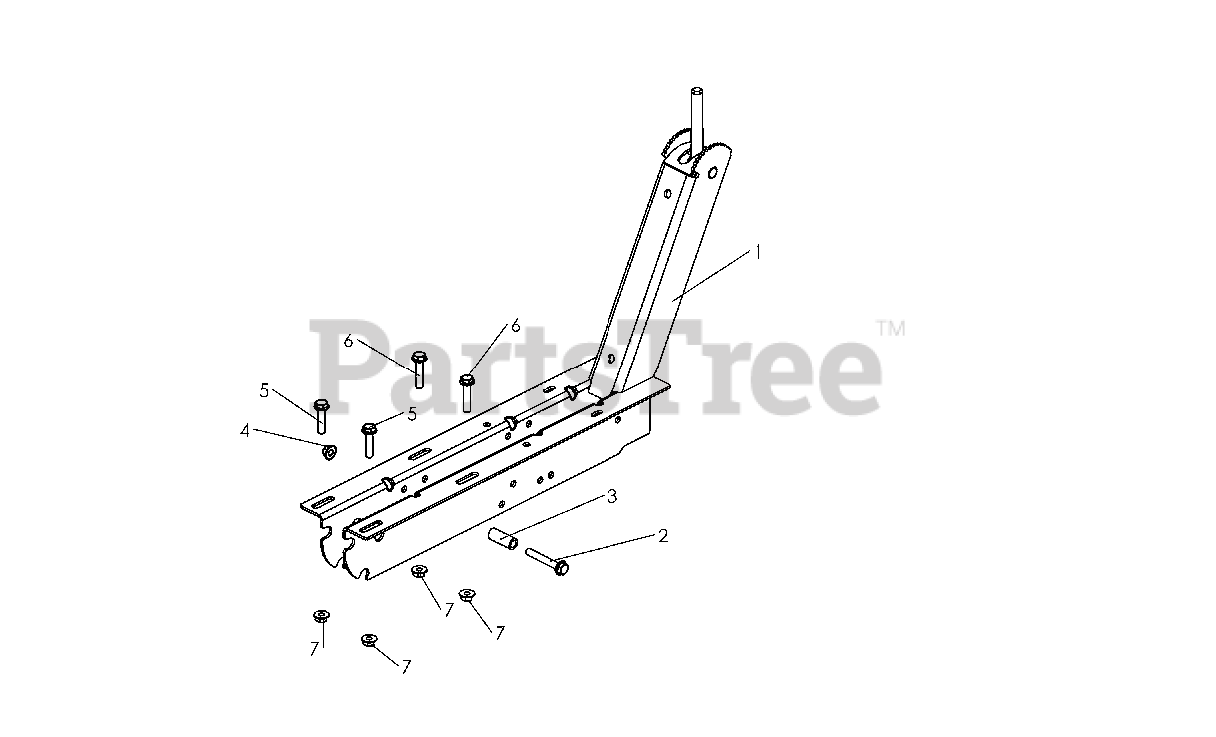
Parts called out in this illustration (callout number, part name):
5	SCREW
6	SCREW
7	NUT
